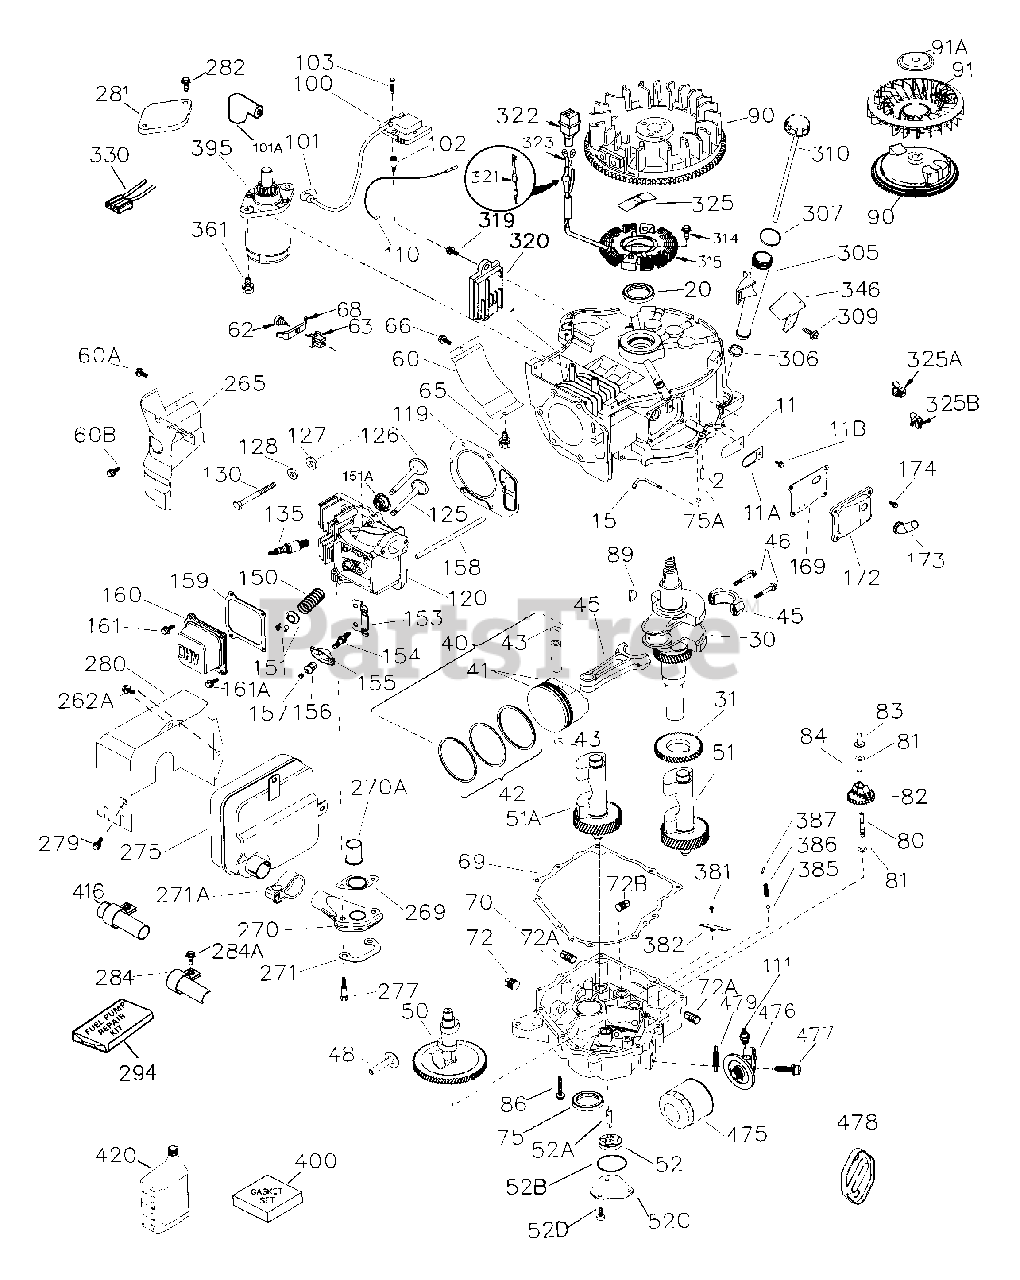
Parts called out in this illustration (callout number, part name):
1	Cylinder
11A	Breather Plate
11B	Screw, 10-32 x 7/16"
15	Governor Rod
31	Counterbalance Gear
40	Piston, Pin & Ring Set (Std.)
40	Piston, Pin & Ring Set (.010" OS)
40	Piston, Pin & Ring Set (.020" OS)
41	Piston & Pin Ass'y (Std.) (.010" OS) (.020" OS)
42	Ring Set (Std.)
42	Ring Set (.010" OS)
42	Ring Set (.020" OS)
43	Piston Pin Retaining Ring
45	Connecting Rod
45	Connecting Rod Ass'y. (.010" US)
45	Connecting Rod Ass'y. (.020" US)
46	Connecting Rod Bolt
48	Valve Lifter
51	Counterbalance Weight
52	Oil Pump Ass'y.
52A	Oil Pump Shaft
52B	"O" Ring
52C	Oil Pump Cover
52D	Screw, T-30, 1/4-20 x 43/64"
60A	Screw, 5-16/18 x 17/32"
60B	Screw, 10-24 x 1/2"
65	Screw, T-30, 1/4-20 x 1/2"
66	Screw, 1/4-20 x 1/2"
69	Mounting Flange Gasket
70	Mounting Flange
72A	Oil Drain Plug
75	Oil Seal 75A TC-510337 Oil Seal
80	Governor Shaft
82	Governor Gear Ass'y.
83	Governor Spool
84	Retaining Ring
86	Screw, 1/4-20 x 1-15/32"
91	Flywheel Fan
91A	Flywheel Fan Retainer
100	Solid State Ignition
101	Spark Plug Cover
102	Solid State Mounting Stud
103	Screw, T-15, 10-24 x 15/16"
119	Cylinder Head Gasket
120	Cylinder Head
125	Exhaust Valve (Std.)
125	Exhaust Valve (1/32" OS)
126	Intake Valve (Std.)
128	Belleville Washer
130	Screw, 5/16-18 x 2-45/64"
135	Resistor Spark Plug (RN4C)
150	Valve Spring
151	Valve Spring Keeper
151A	Intake Valve Seal
153	Push Rod Guide
154	Rocker Arm Stud
156	Rocker Arm Bearing
159	Rocker Arm Cover Gasket
160	Rocker Arm Housing
161	Screw, T-30, 1/4-20 x 1/2"
169	Breather Gasket
173	Breather Tube
174	Screw, T-30, 1/4-20 x 1/2"
265	Cylinder Head Cover
270A	Exhaust Port Liner
294	Pulse Pump Repair Kit
305	Oil Fill Tube
306	"O" Ring
309	Screw, 1/4-20 x 57/64"
314	Screw, T-15, 10-24 x 15/16"
315	Alternator Coil (3/5 Split)
322	Connector Body
346	Fuel Pump Bracket
361	Screw, 15/16-18 x 29/32"
381	Screw, 8-32 x 27/64"
382	Oil Strainer Screen
386	Pressure Relief Spring
395	Electric Starter Motor (12 Volt)
400	Gasket Set
420	SAE 30 4-Cycle Engine Oil (Quart)
476	Oil Filter Adapter
477	Screw, T-30, 5/16-18 x 2"
479	Oil Filter Adapter Gasket
